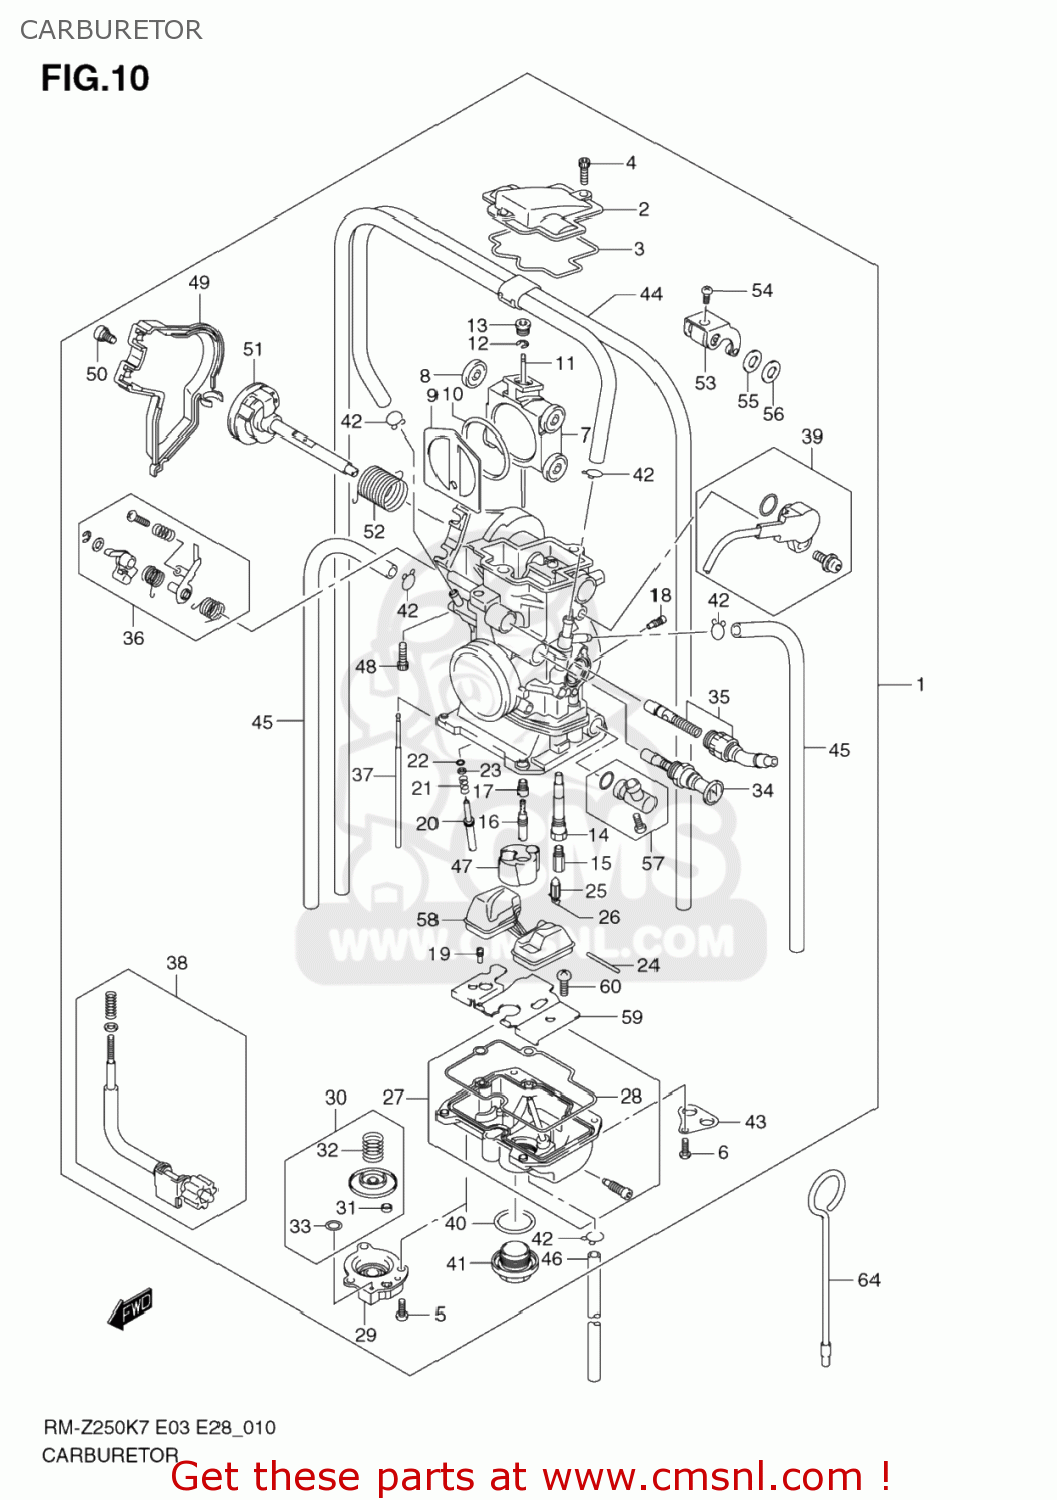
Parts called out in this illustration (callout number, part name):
1	CARBURETOR ASSY
2	TOP
3	O RING
4	BOLT(4X12)
5	SCREW
6	SCREW
7	THROTTLE VALVE
8	BEARING
9	FLOATING VALVE
10	LIP SEAL
11	NEEDLE,JET(NLCT)
12	BAR,CLIP
13	SCREW SET,JET,NEEDLE
14	MAIN NOZZLE
15	JET,MAIN(162)
16	JET,SLOW(42)
17	JET,STARTER
18	JET,SLOW AIR
19	JET
20	SCREW,ADJUST
21	SPRING
22	O RING
23	WASHER
24	PIN,FLOAT
25	VALVE,FLOAT
26	CLIP
27	FLOAT,CHAMBER BODY SET
28	O RING
29	COVER
30	DIAPHRAGM SET
31	U RING
32	SPRING
33	O RING
34	STARTER VALVE
35	STARTER VALVE
36	LEVER SET,LINK
37	ROD
38	SCREW SET
39	SENSOR SET,THROTTLE
40	O RING
41	BOLT,DRAIN
42	CLIP
43	PLATE
44	PIPE SET,BOWL VENT
45	PIPE
46	PIPE
47	PLATE,BUFFER
48	SCREW
49	COVER
50	BOLT
51	THROTTLE SHAFT
52	SPRING
53	LINK ARM
54	SCREW
55	WASHER
56	WASHER
57	JOINT SET
58	FLOAT
59	PLATE,BUFFER
60	SCREW
61	JET,MAIN(150)
62	JET,SLOW(35)
63	NEEDLE,JET(NLCR)
64	HOLDER,JET NEEDLE
